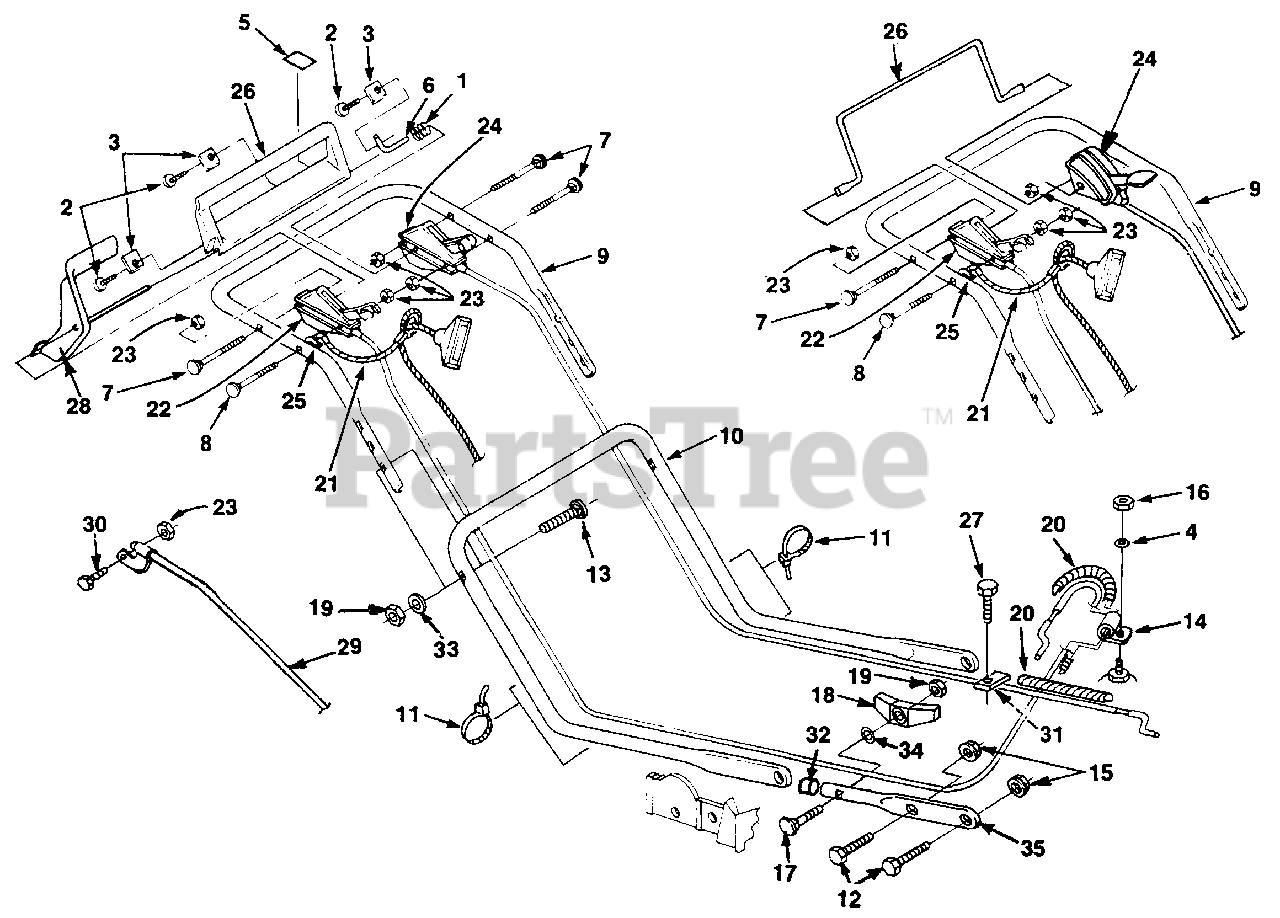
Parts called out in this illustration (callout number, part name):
1	SPRING- Compression
2	SCREW- 1/4-1 0 x 5/8"
3	CLAMP- Pivot shaft
4	WASHER- Lock 1/4"
5	DECAL- Warning
6	SHAFT- Pivot
7	BOLT- Sq. nk.
8	BOLT- Sq. nk.
9	HANDLE- Upper
10	HANDLE- Lower
11	CABLE- Tie
12	BOLT- Hex 16-18 x 1"
13	SCREW- 5/16-18 x 1 1/2"
15	NUT- Flange 5/16-18
16	NUT- Hex 1/4-20
17	BOLT- Handle joining
18	KNOB- Handle
19	NUT- Hex 5/16-18
20	COVER- Cable
21	GRIP- Restraint
22	ENGINE CONTROL
23	NUT- Lock 1/4-20
24	CONTROL- Throttle
26	BAIL- Brake control
27	SCREW- Hex 1/4-20 x 5/8"
28	TRACTION LEVER ASSY.
29	CABLE- Traction control
30	SCREW- 1/4-20 x 1 1/2"
32	PLUG- Cap
33	WASHER- Lock 5/16-18
34	WASHER- Flat 5/16
35	STUB- Handle mtg.
